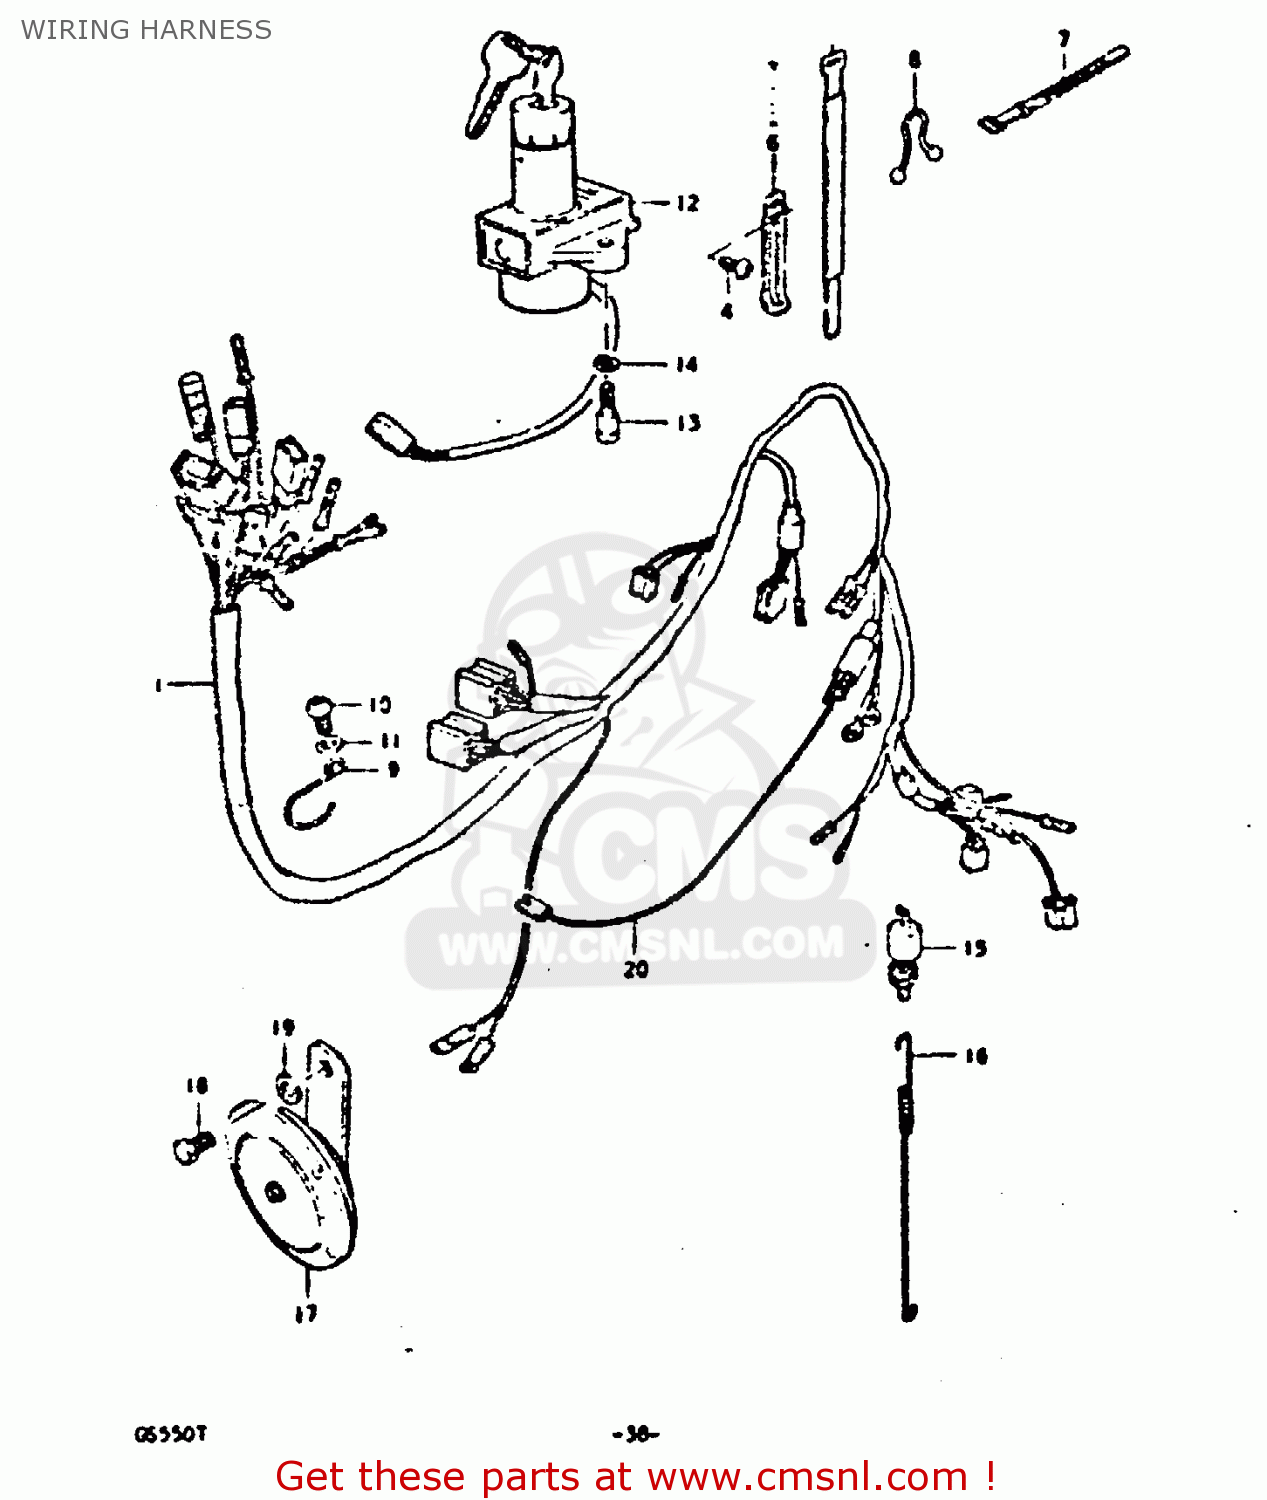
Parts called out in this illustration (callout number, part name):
1	WIRING HARNESS
2	CLAMP
3	CLAMP
4	SCREW
5	CLAMP
6	CLAMP
7	CLAMP(L:120)
8	CLAMP
9	GUIDE,WIRING HARNESS
10	SCREW 6X12
11	WASHER
12	LOCK ASSEMBLY,STEERING
13	BOLT
14	LOCK WASHER
15	SWITCH ASSY,BRAKE LAMP
16	SPRING
17	HORN ASSEMBLY,LOW PITCH
18	BOLT 8X12
19	WASHER
20	WIRE
